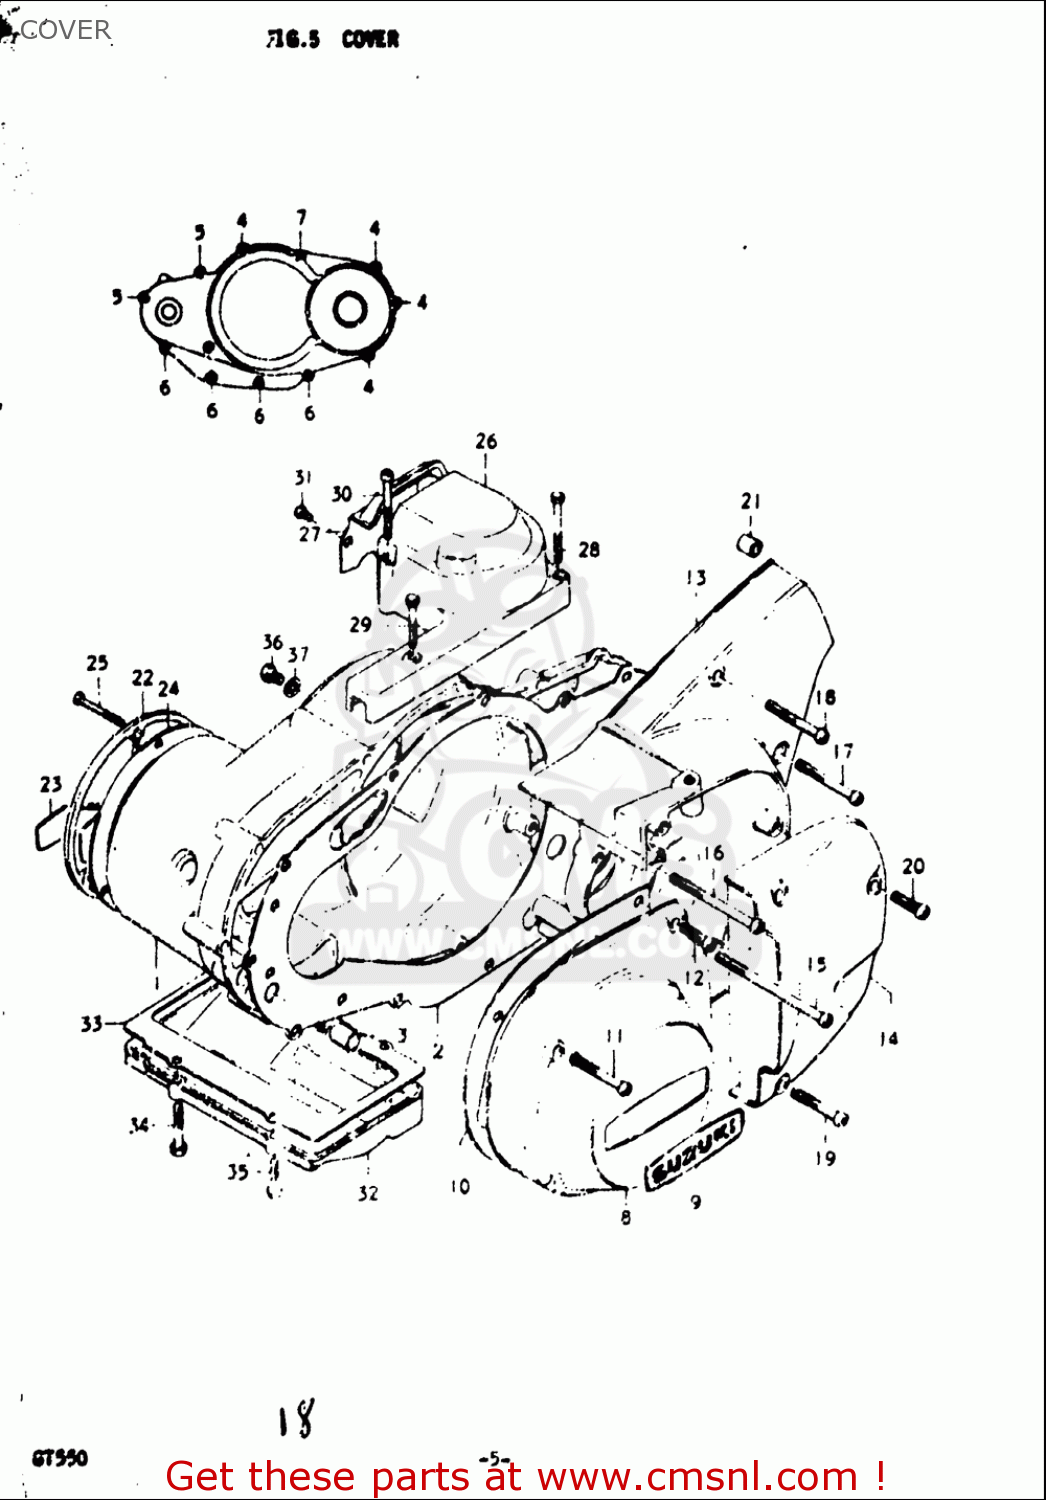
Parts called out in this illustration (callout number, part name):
2	GASKET,CLUTCH COVER
3	PIN
4	SCREW
5	SCREW
6	SCREW
7	SCREW
9	EMBLEM,CONTACT BREAKER CAP
10	GASKET,MAGNETO COVER (MCA)
11	SCREW
12	SCREW
15	SCREW
16	SCREW
17	SCREW
18	SCREW
19	SCREW
20	SCREW
21	PIN
23	EMBLEM,CONTACT BREAKER CAP
24	GASKET,CONTACT BREAKER CAP (NAS)
25	SCREW
28	BOLT 5X45
29	BOLT
30	SCREW
31	SCREW
34	BOLT
35	BOLT 5X20
36	SCREW(6X10)
37	WASHER
